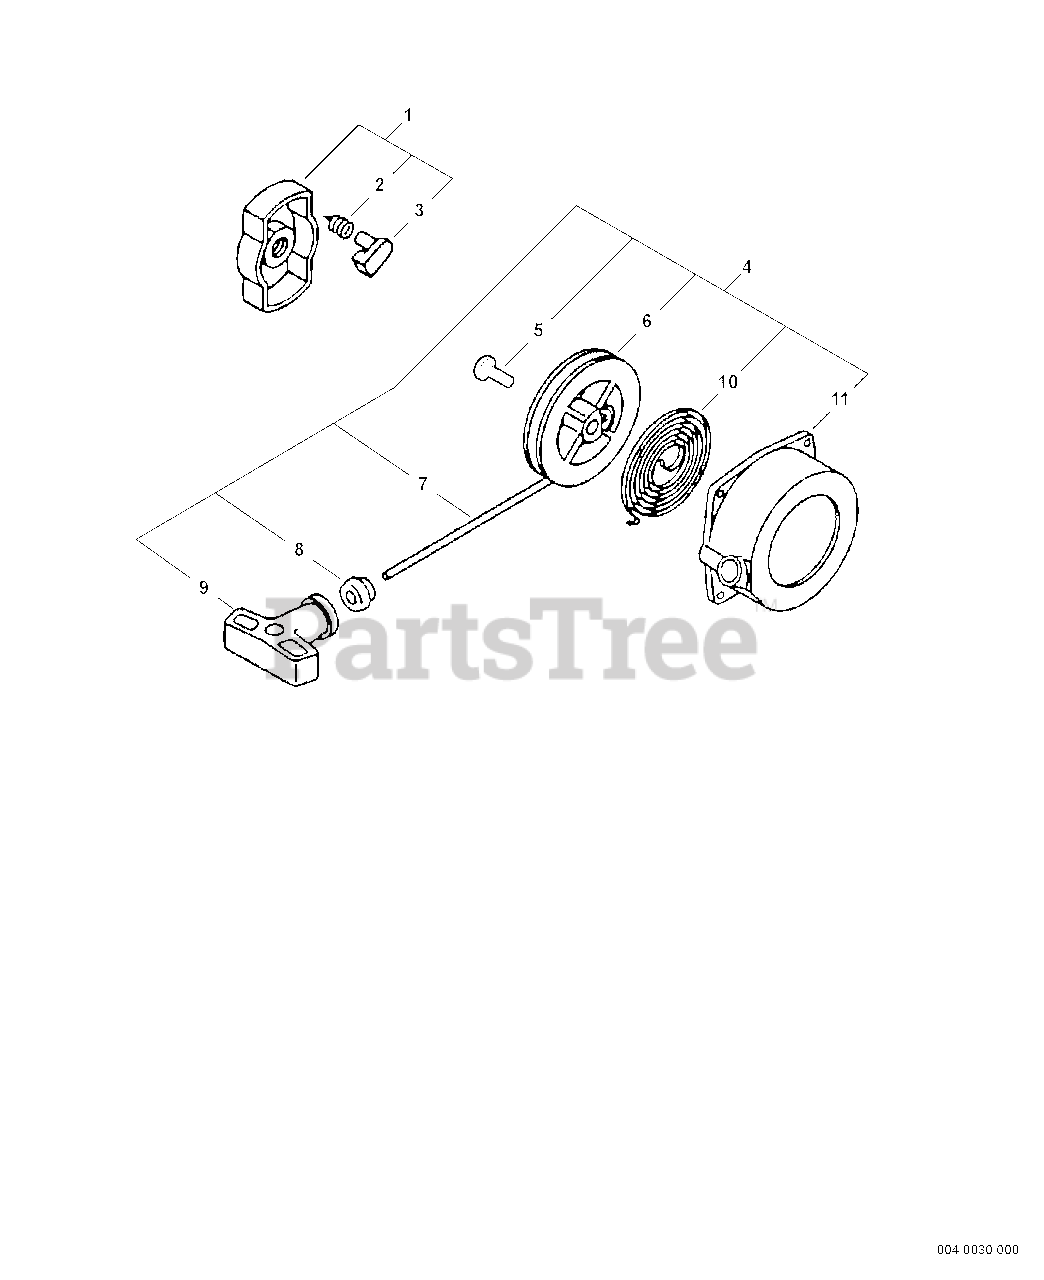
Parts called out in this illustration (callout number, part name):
1	PAWL ASSY, STARTER
2	SPRING, RETURN
3	PAWL, STARTER - BLACK
4	STARTER ASSY, RECOIL
5	SCREW
6	REEL, ROPE
7	ROPE, STARTER 3.0×1000
8	GUIDE, ROPE
9	GRIP, STARTER
10	SPRING, RECOIL
11	CASE, RECOIL STARTER
